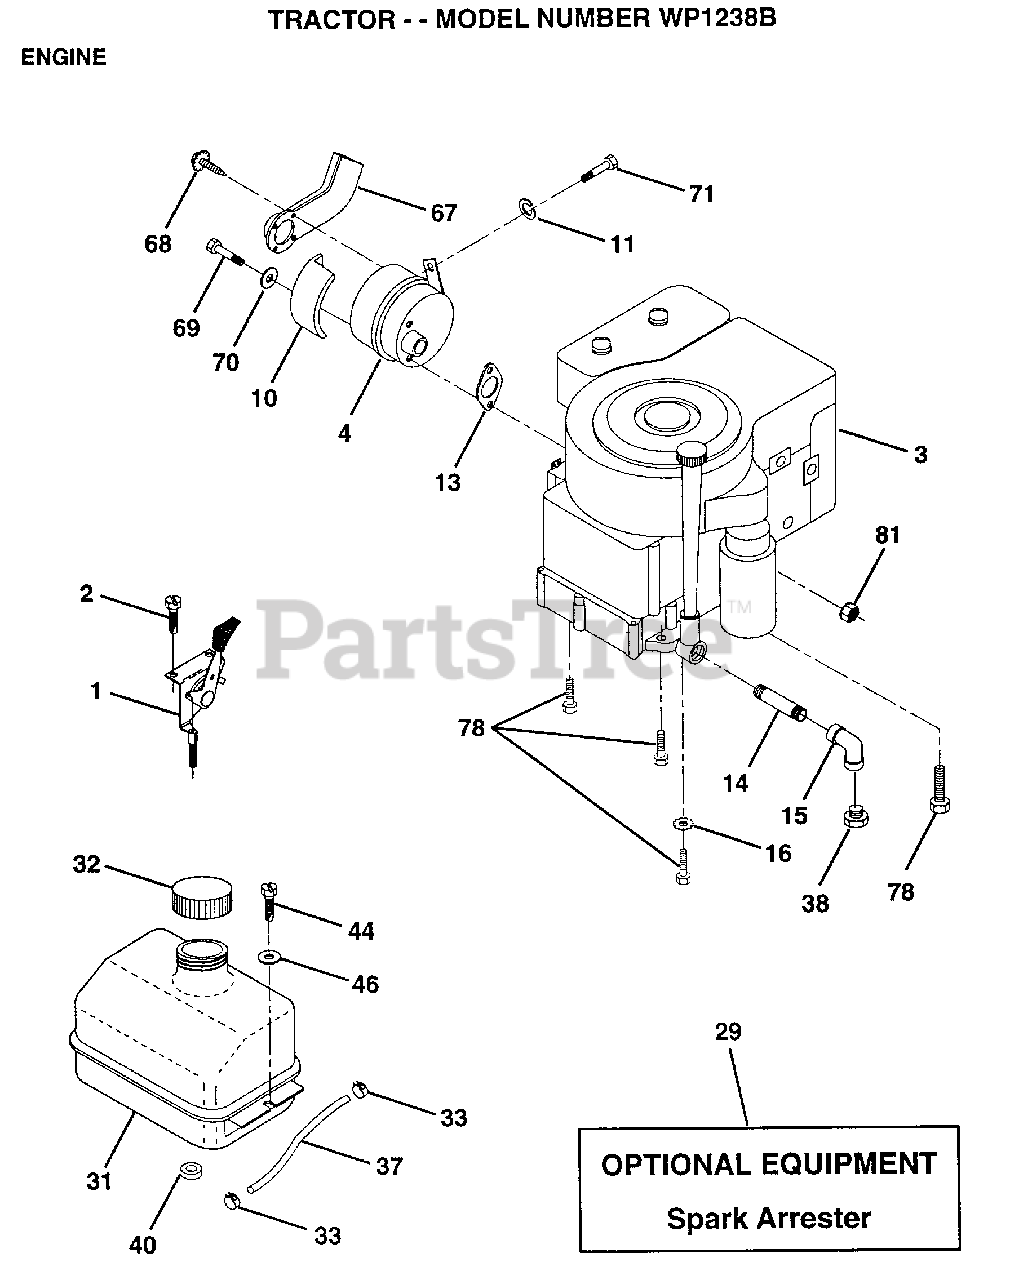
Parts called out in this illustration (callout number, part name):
1	THROTTLE CONTROL
2	SCREW LT
4	MUFFLER LTV
10	SHIELD HEAT LTV
11	LOCKWASHER
13	GASKET ENG 1 313 LD TIN PLATED
14	PIPE NIPPLE
15	ELBOW
16	LOCKWASHER
31	TANK.FUEL.LT.
32	CAP ASM FUEL
33	HOSE CLAMP
37	LINE FUEL
44	SCREW HEX CRT
46	WASHER
67	DEFLECTOR MUFFLER
69	"BOLT,HEX"
70	WASHER T
71	BOLT HXHD FIN
78	SCREW
81	NUT
